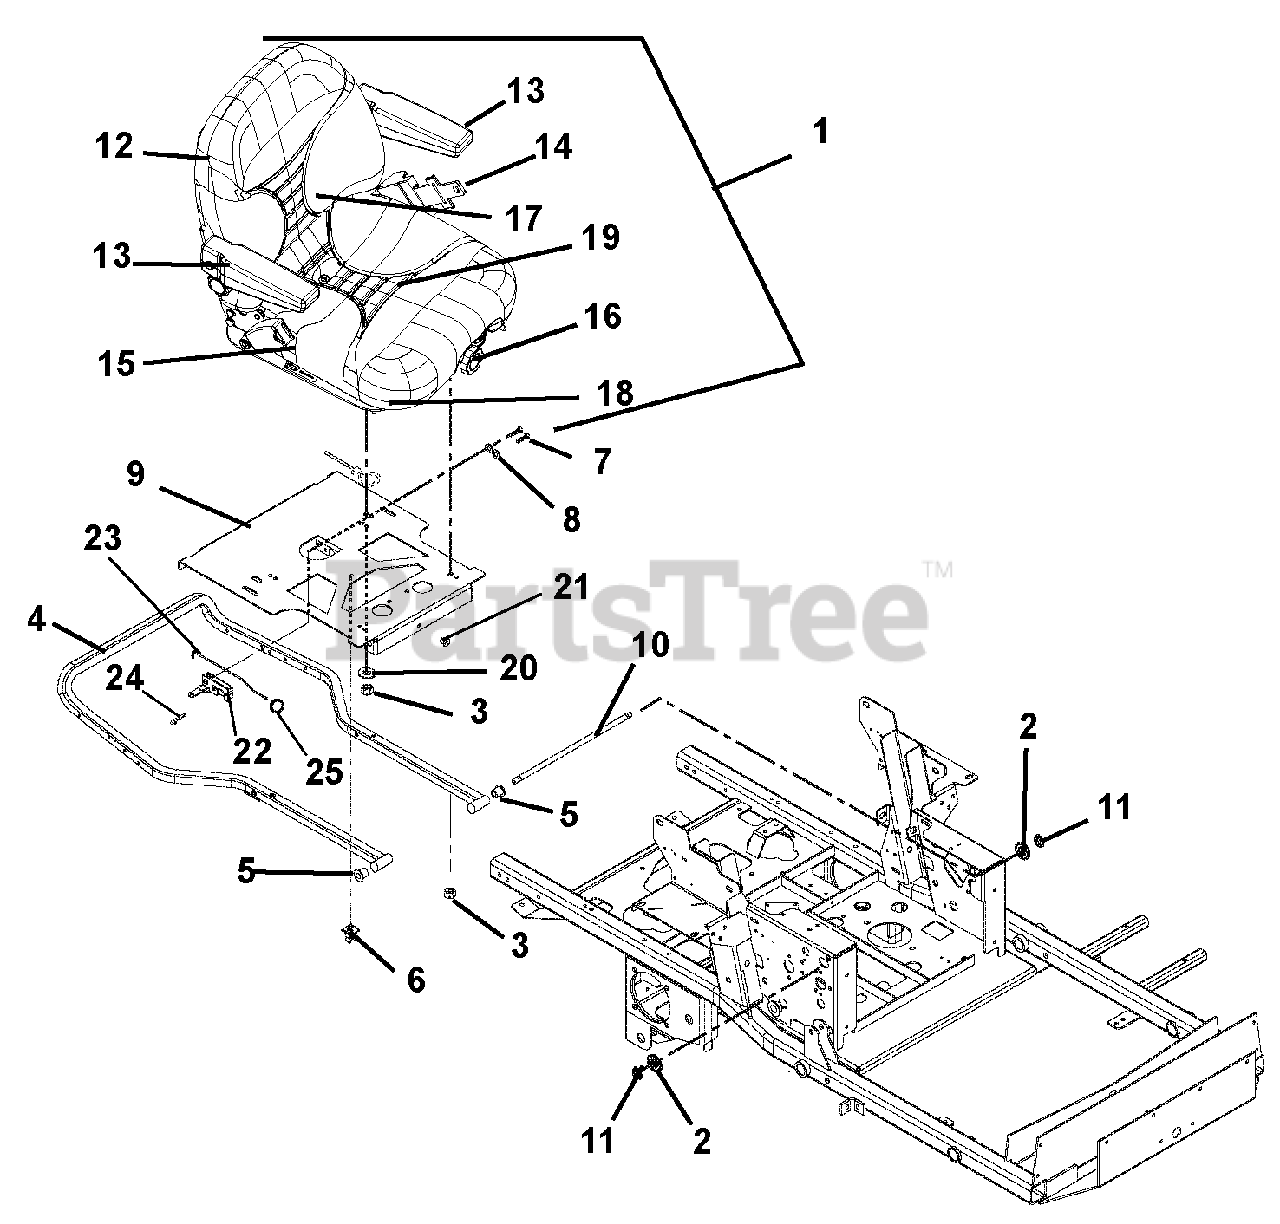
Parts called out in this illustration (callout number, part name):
1	Seat, w/Seat Belt, Gray
2	Washer, Flat Steel .531 x 1.06 x .095
3	Nut, Locking Top Flange .31-18
4	Weldment, Hood Frame
5	Bushing, Flange .515 x .750 x .745 x 1.00
6	Clip, Routing
7	Bolt, Hex .25-20 x 1.00 Grade 5
8	Washer, Locking .25 x .062 Regular
9	Plate, Seat 200 XDZ with Latch
10	Rod, Seat Frame Pivot
11	Ring, Retaining External .500 x .050
12	Kit, Back Cushion, Gray
13	Kit, Armrest, Plush 5300 Pair
14	Kit, Retractable Safety Belt
15	Kit, Seat Cushion, Light Gray
16	Kit, Seat Knobs
17	Kit, Seat Back
18	Kit, Seat Slides
19	Kit, Seat, Spring and Saddle
20	Washer, Flat Steel .344 x 1.25 x .135
21	Bushing, POLYLINER-.38 SNAPIN
22	Latch, Rotary-Push To Close
23	Rod, Seat Latch Release
24	Pin, Hair Internal .06 x .25 x 1.12
